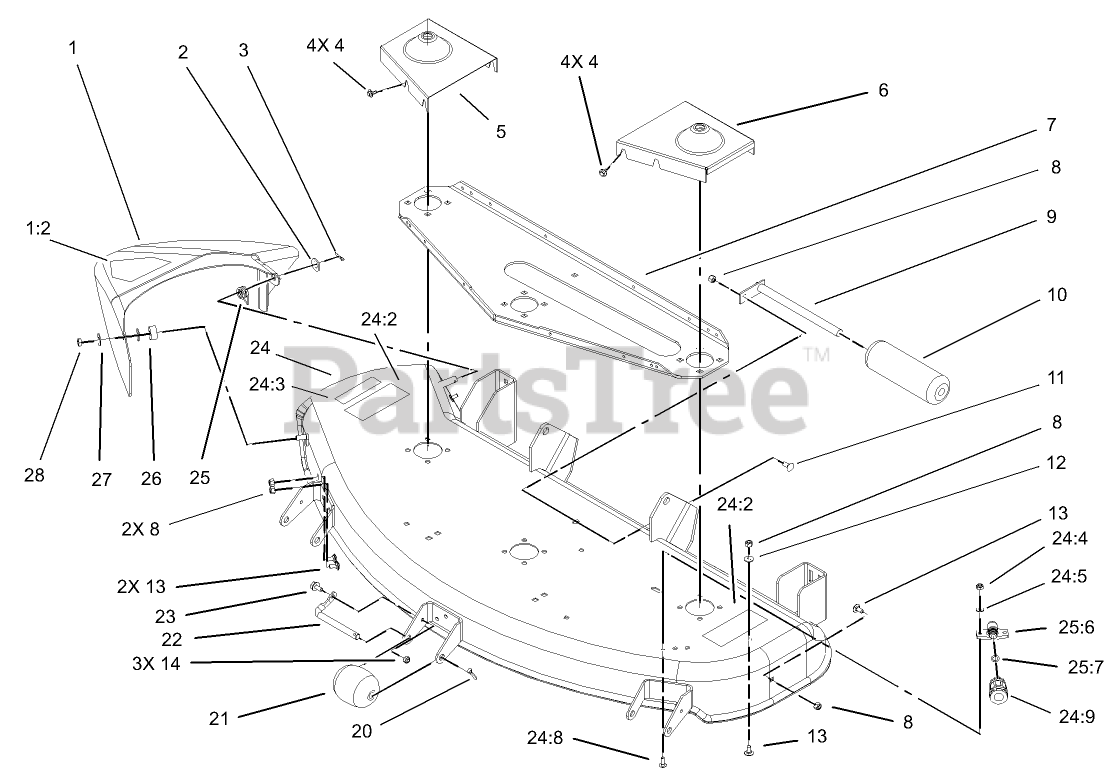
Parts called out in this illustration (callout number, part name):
1	CHUTE ASM
1:2	DECAL-DANGER
2	WASHER-FLAT
3	PIN-COTTER
4	SCREW-HHFTF
5	COVER-BELT, RH
6	COVER-BELT, LH
7	PLATE-REINFORCEMENT,DECK
8	NUT-LOCK, NI
9	ROLLER-SHAFT
10	ROLLER-ANTI SCALP
11	BOLT-CARR
12	WASHER-FLAT
13	SCREW-CARR
14	NUT-LOCK, NI
20	PIN-COTTER
21	ROLLER
23	SCREW-HH
24	48IN DECK/DECAL ASM
24:2	DECAL-DANGER
24:3	DECAL-CAUTION
24:4	NUT-LOCK, NI
24:5	WASHER-FLAT
24:7	O-RING
24:8	BOLT-CARR
24:9	CONNECTOR-HOSE
25	SPRING-DEFLECTOR
26	BUSHING-PIVOT
27	WASHER
28	NUT-HJ
